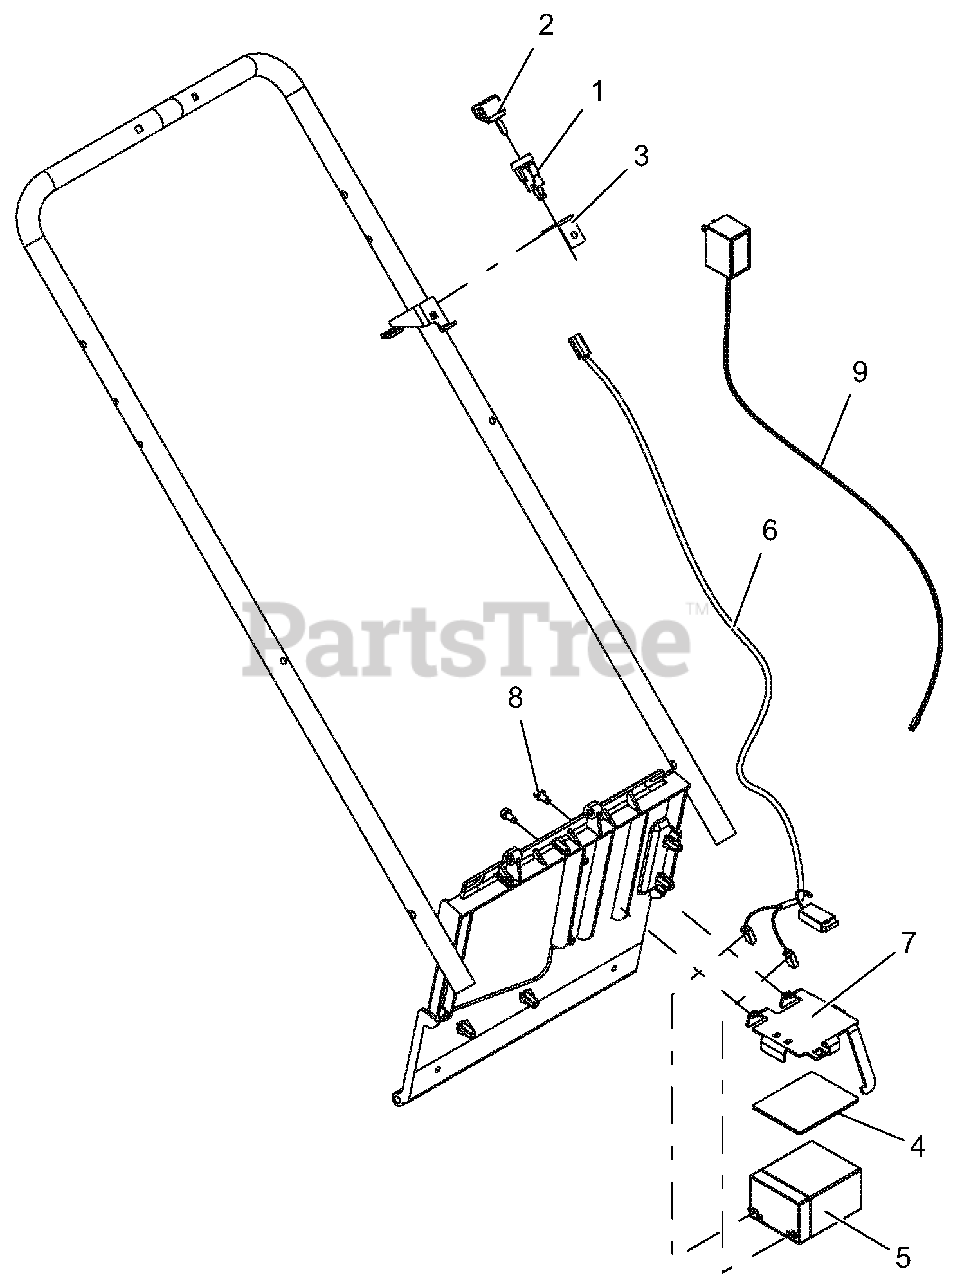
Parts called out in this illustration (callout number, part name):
1	SWITCH, KEY
2	KEYS, IGNITION
3	BRKT, KEY SWITCH
4	PAD, BATTERY, LM
5	BATTERY, AGM, 2.9AH, GNRL PRPS
6	HARNESS, ELEC START
7	BRKT, BATTERY HOLD DOWN
8	SCR-TAP .25-20X.50 HWH TR YWZ
9	CHARGER, BATTERY
